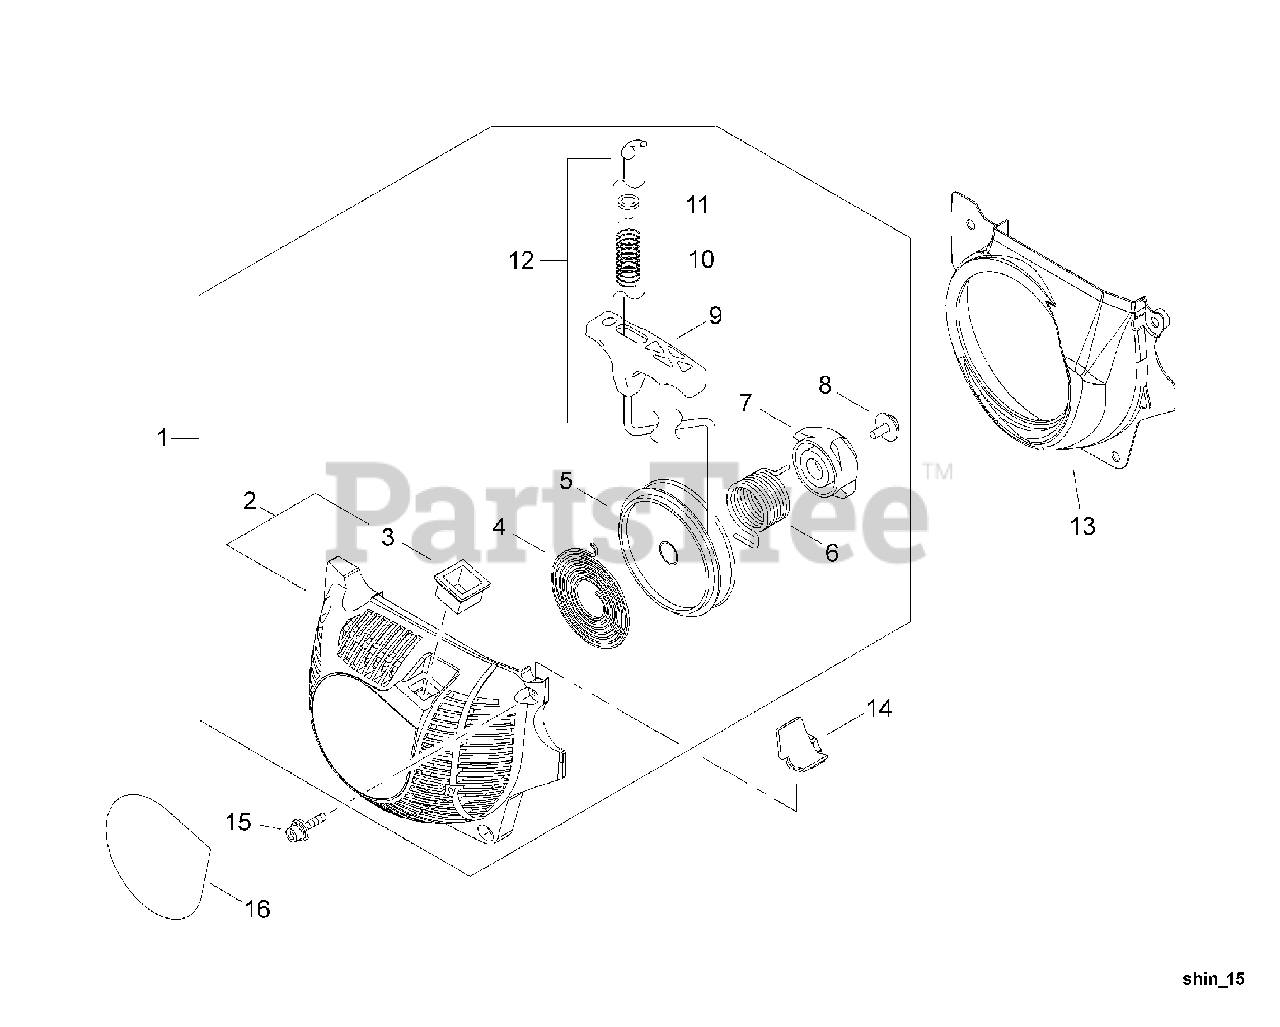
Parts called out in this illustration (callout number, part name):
1	STARTER ASSY, RECOIL
2	CASE ASSY, RECOIL STARTER
3	GUIDE, ROPE
4	SPRING, RECOIL
5	REEL, ROPE
6	SPRING, TORSION Ø2.6
7	PAWL CATCHER
8	SCREW 5
9	GRIP, STARTER
10	SPRING, COMPRESSION
11	RETAINER, ROPE
12	ROPE, STARTER Ø3.8×750
13	COVER, FAN
14	GROMMET, STARTER CASE
15	BOLT M4×16
16	LABEL, MODEL - 502
